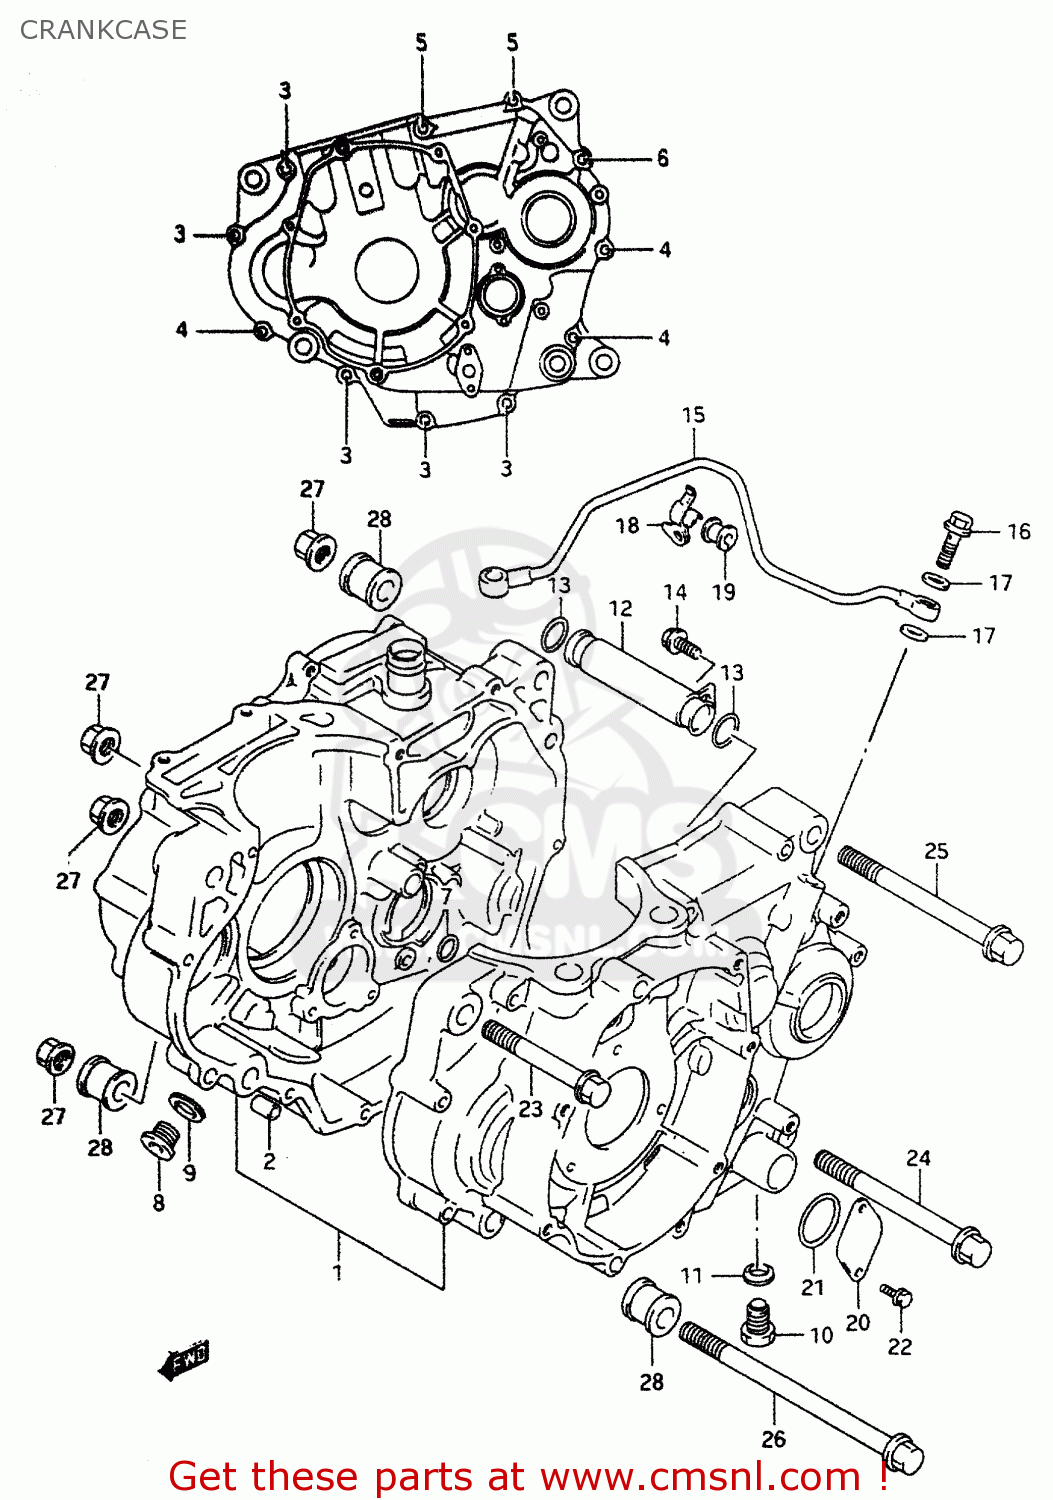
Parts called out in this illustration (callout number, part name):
1	CRANKCASE SET
2	PIN
3	BOLT
4	BOLT
5	BOLT
6	BOLT
7	O RING(D:1.9,ID:12.6)
8	PLUG,14X12
9	GASKET(13.8X18.8X4.8) (NAS)
10	BOLT
11	GASKET(12.1X16.2X3.7) (NAS)
12	PIPE,T/M OIL INNER
13	O RING(D:2.4,ID:15.8)
14	BOLT
15	PIPE,T/M OIL OUTER
16	BOLT UNION
17	GASKET 8.2X14X1 (NAS)
18	CLAMP,OIL PIPE
19	CUSHION
20	CAP,NEUTRAL SWITCH HOLE
21	O RING(D:2.4,ID:26.2)
22	BOLT
23	BOLT 10X85
24	BOLT(10X101.5)
25	BOLT(10X115)
26	BOLT(10X143)
27	NUT
28	SPACER,ENGINE MOUNTING
